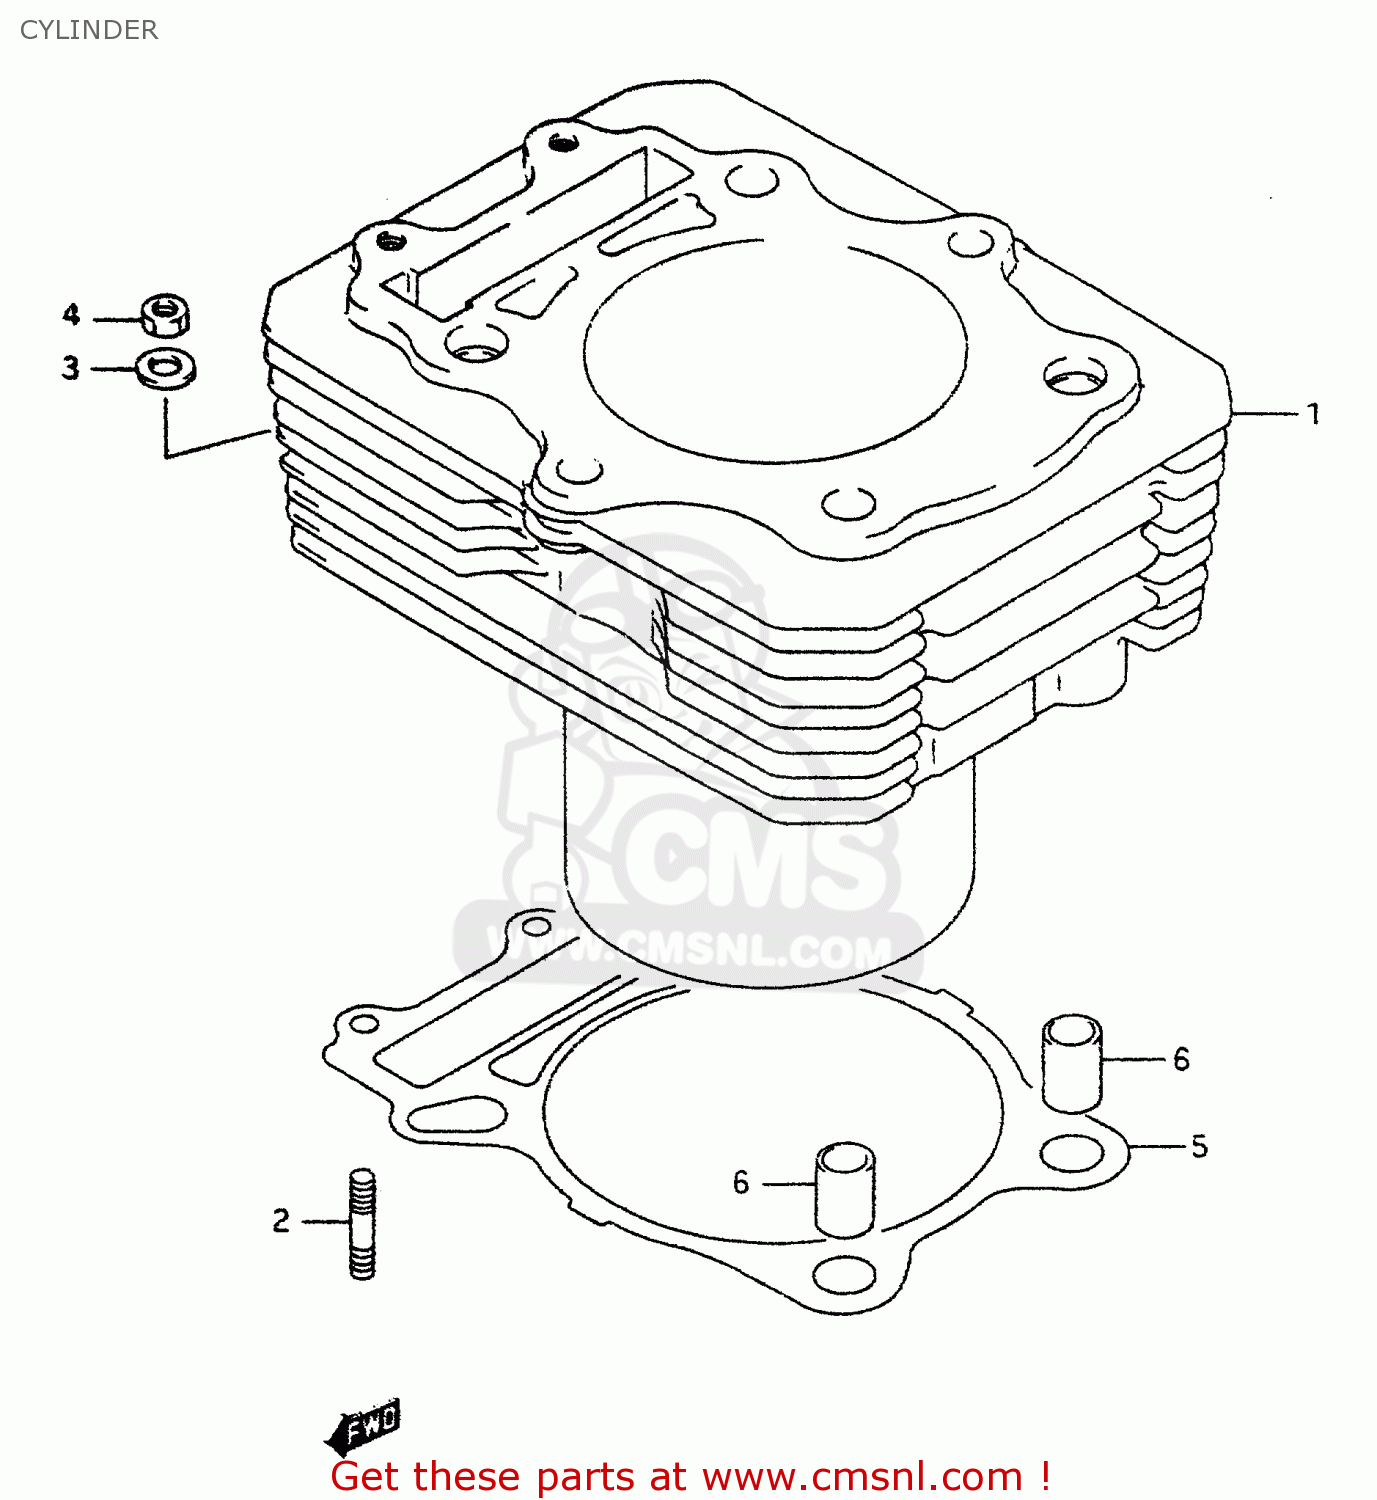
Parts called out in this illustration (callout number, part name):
1	CYLINDER
2	STUD 6X20
3	WASHER
4	NUT
5	GASKET,CYLINDER (NAS)
6	PIN
